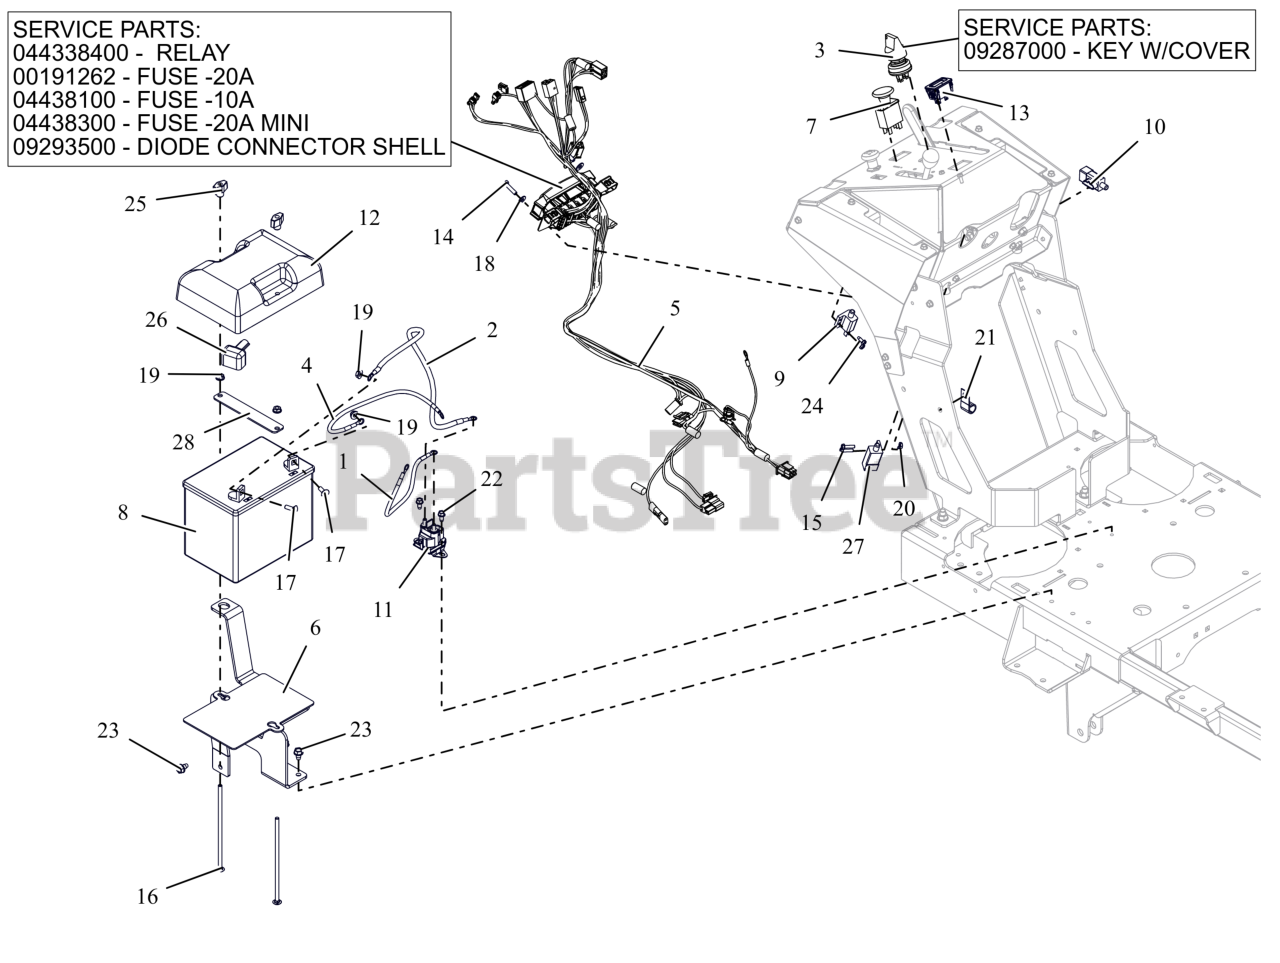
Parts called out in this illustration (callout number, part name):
1	CABLE-POSITIVE BATTERY 9.00"
2	CABLE - START 22.00"
3	SWITCH, IGNITION
3	KEY, W/ SHIELD
4	CBL,NEGATIVE BATTERY 20.00
5	HARNESS, 36-60 PRO-WALK
5	FUSE, 20 AMP BLADE S/O
5	FUSE,10 AMP MINI-ATC
5	FUSE,20 AMP MINI ATC
5	DIODE, CONNECTOR SHELL
6	WLDMT, BATTERY TRAY (RED)
7	SWITCH, CLUTCH
8	BATTERY, 300 CCA 10U1L
9	SWITCH- SINGLE POLE N.O.
10	SWITCH, SNAP IN - N.O./N.O.
11	SOLENOID, STARTER (SEALED)
12	COVER, BATTERY
13	HOUR METER
14	BLT, HEX M6-1.0 X 25 G8.8 ZCC
15	BLT, HWH #10-24X.75 ZCC
16	BLT,RHSN .25-20X7.00 G2 ZCC
17	BLT, RHSN .25-20X.750 G5 ZCC
18	WSHR,FLT .281X.625X.065 ZCC
19	NUT-SPNLK-FLG .25-20 ZC120
20	NUT, HEX .250-20 GR5 ZCC
22	SCR-TAP .25-20X.50 HWH ZCC
23	SCR,TAP .312-18X.50 HWH TR ZCC
24	SCR,TAP #10-24X.50 HWH TR ZCC
25	KNOB, WING - .25-20 UNC
26	INSULATOR
27	SWITCH,INTERLOCK
28	STRAP, BATTERY
